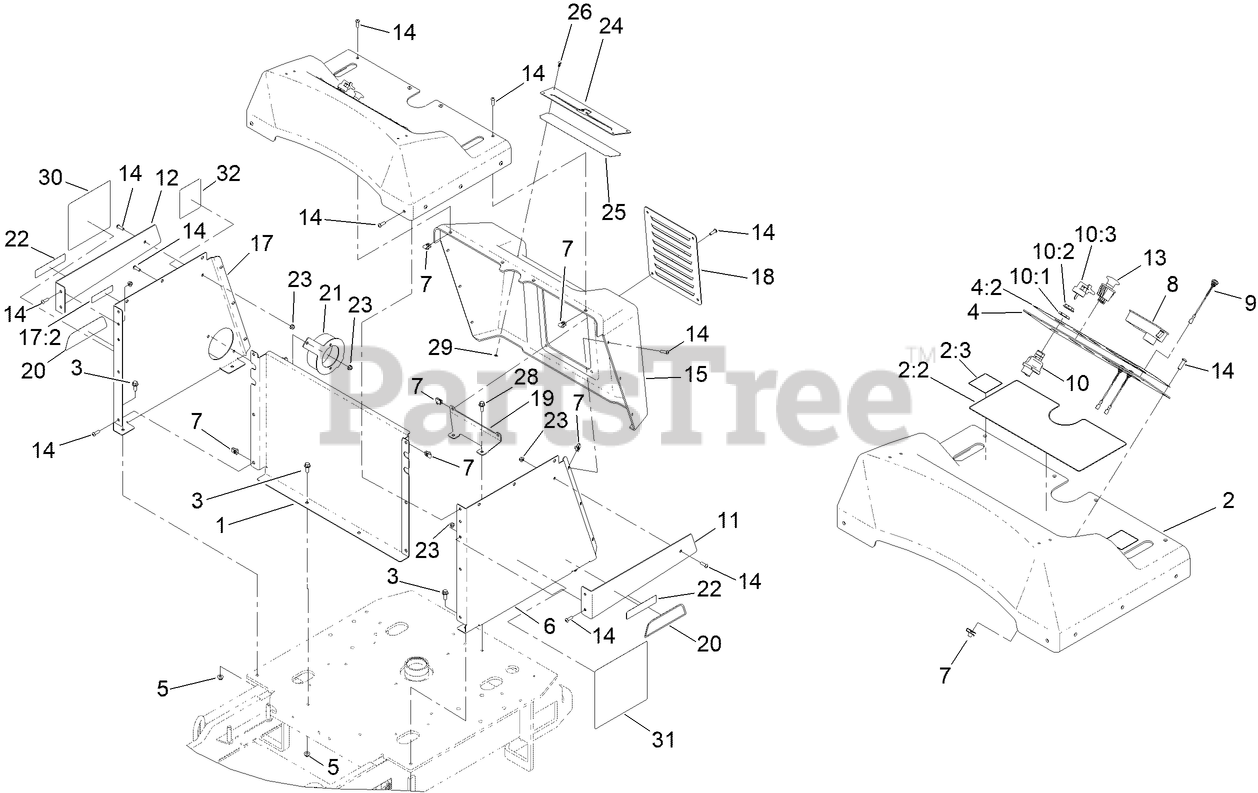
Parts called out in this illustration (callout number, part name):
1	PANEL-TOWER,FRONT
2	DASH PANEL ASM
2:2	DECAL-CONTROL PANEL
2:3	DECAL-LIFT HERE
3	SCREW-HHF
4	DISPLAY COVER ASM
4:2	DECAL-CONTROL PANEL
5	NUT-HF, NI
6	PANEL-ACCESS, LH
7	NUT-U
8	CONTROLLER, TDM-1601
9	SWITCH-PUSHBUTTON
10	SWITCH-IGNITION, SUNS
10:1	NUT-HEX
10:2	NUT-FACE, M22 (PLASTIC)
10:3	SET-KEY, IGNITION
11	PLATE-DECAL [BLK-TXT]
12	PLATE-DECAL [BLK-TXT]
13	SWITCH, E-STOP
14	SCREW-HSBH
17	ACCESS PANEL ASM, RH
17:2	DECAL-SERVICE, SHUT-OFF
18	COVER-ACCESS
19	BRACKET-HOOD
20	DECAL-HYPERCELL
21	BRACKET-DISCONNECT [BLK-TXT]
22	DECAL-E2500
23	NUT-HF, NI
24	PLATE-LOGO
25	DECAL-BACKER, RED
26	RIVET-POP
28	SCREW-HWH
29	WASHER-PLAIN
30	DECAL-S8VSW8X8
31	DECAL-S8VSW10X10
32	DECAL-TELEMATICS-SBR
